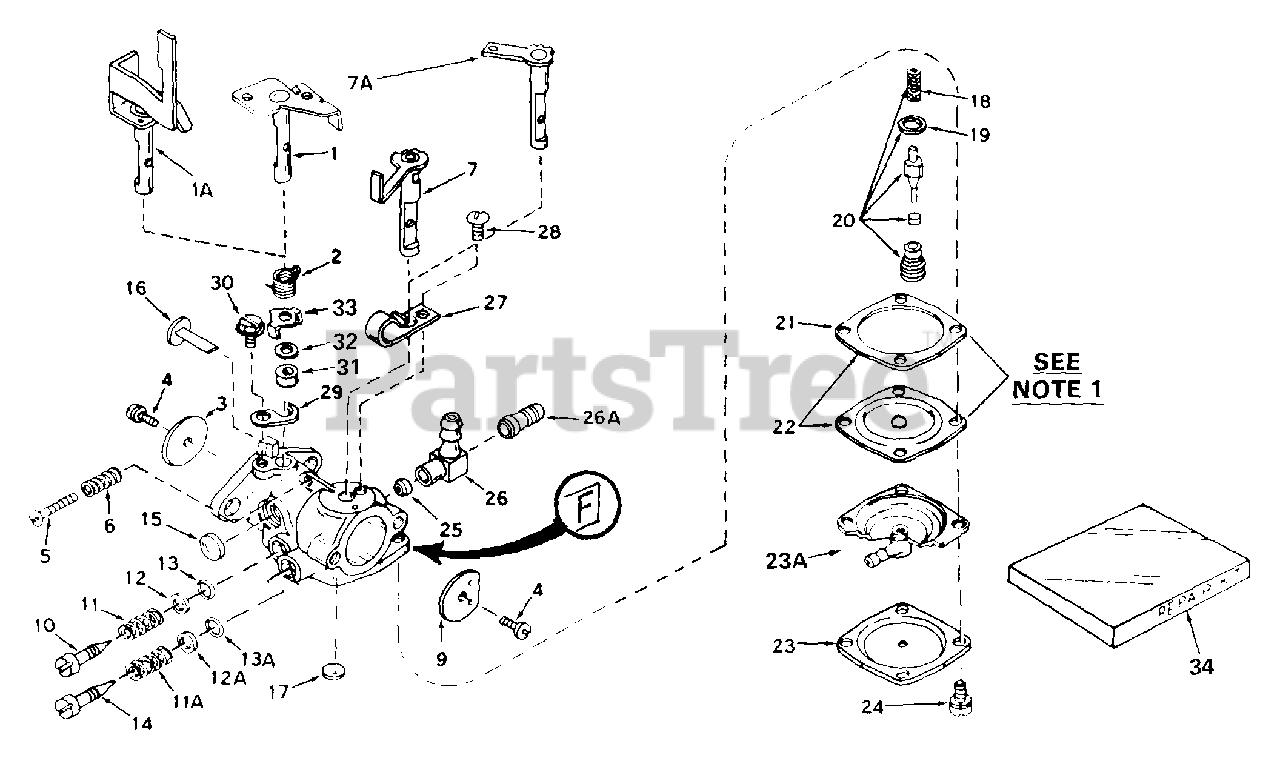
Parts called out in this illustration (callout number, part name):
1	"Shaft & Lever Assy., Throttle
2	Spring, Throttle return
3	Shutter, Throttle
4	Screw, Throttle & Choke shutter
5	Screw, Idle regulating
6	Spring, Idle speed screw
7A	Shaft & Lever Assy., Choke
9	Shutter, Choke
10	Screw, Idle adj.
11	Spring, Idle adj. screw
11A	Spring, Main adj. screw
12	Washer, Idle adj. screw
12A	Washer, Main adj. screw
13	"O" Ring, Idle adj. screw
13A	"O" Ring, Main adj. screw
14	Screw, Main adj. (.0225 dia. hole)
15	Plug, Welch
16	Element, Pump
17	Plug, Welch
18	Spring, Valve
19	Gasket, Valve seat
20	Inlet Needle, Seat, Gasket & Spring A ssy.
21	Gasket, Diaphragm
22	Diaphragm Assy.
23	Cover, Diaphragm
24	Screw, Cover
25	Valve, Check
26	Fitting, Fuel inlet
27	Spring, Detent
28	Screw, Detent spring
29	Retainer, Throttle shaft
30	Screw, Retainer
34	Repair Kit
